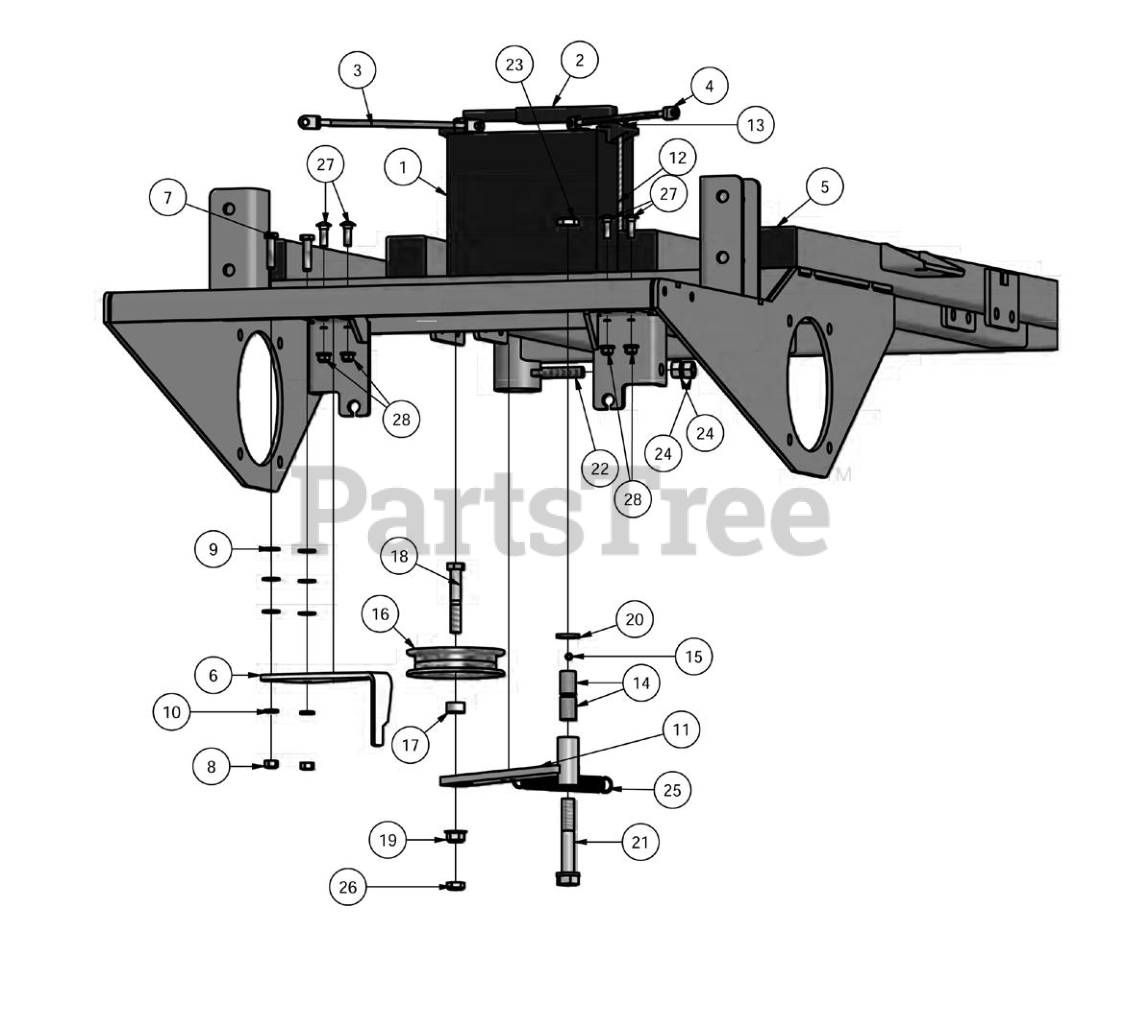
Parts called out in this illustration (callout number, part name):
1	Workaholic
2	Battery Hold Down
3	24" Red Cable
4	Ground Cable
5	2x2 Square Plug
6	PTO Engager Holder
7	3/8-16 x 1-1/2 GR5 Hex Bolt
8	3/8-16 Hex Nuts Zinc
9	3/8 USS Flat Washer Zinc
10	3/8 Lockwasher Zinc
11	Deck Idler Bracket
12	1/4-20 x 8 Carriage Bolt Zinc
13	1/4-20 Wing Nut Zinc
14	Brass Bushing- 5/8 x 1 1/8- SS-2024-18
15	1/4" Drive in Grease Fitting
16	4 3/4" Idler Pulley
17	1/2" Set collar
18	1/2 x 3 Grade 5 Hex Bolt
19	1/2-13 Nylon Insert Flange Nut Zinc Orange Nylon
20	.630 ID X 1.122 OD X.142 THK Flat Washer Nylon
21	5/8-11 X 4 GR 5 Hex Bolts Zinc
22	6 Pump Idler Spring
23	5/8-11 Nylon Insert Jam Locknut Zinc
24	1/2-13 Hex Nuts Zinc
25	Deck Idler Spring
26	1/2-20 Nylon Insert Jam Locknut Zinc Orange Zinc
27	5/16-18 x 1 Carriage Bolts Zinc
28	5/16" Nylock Flange Nut
